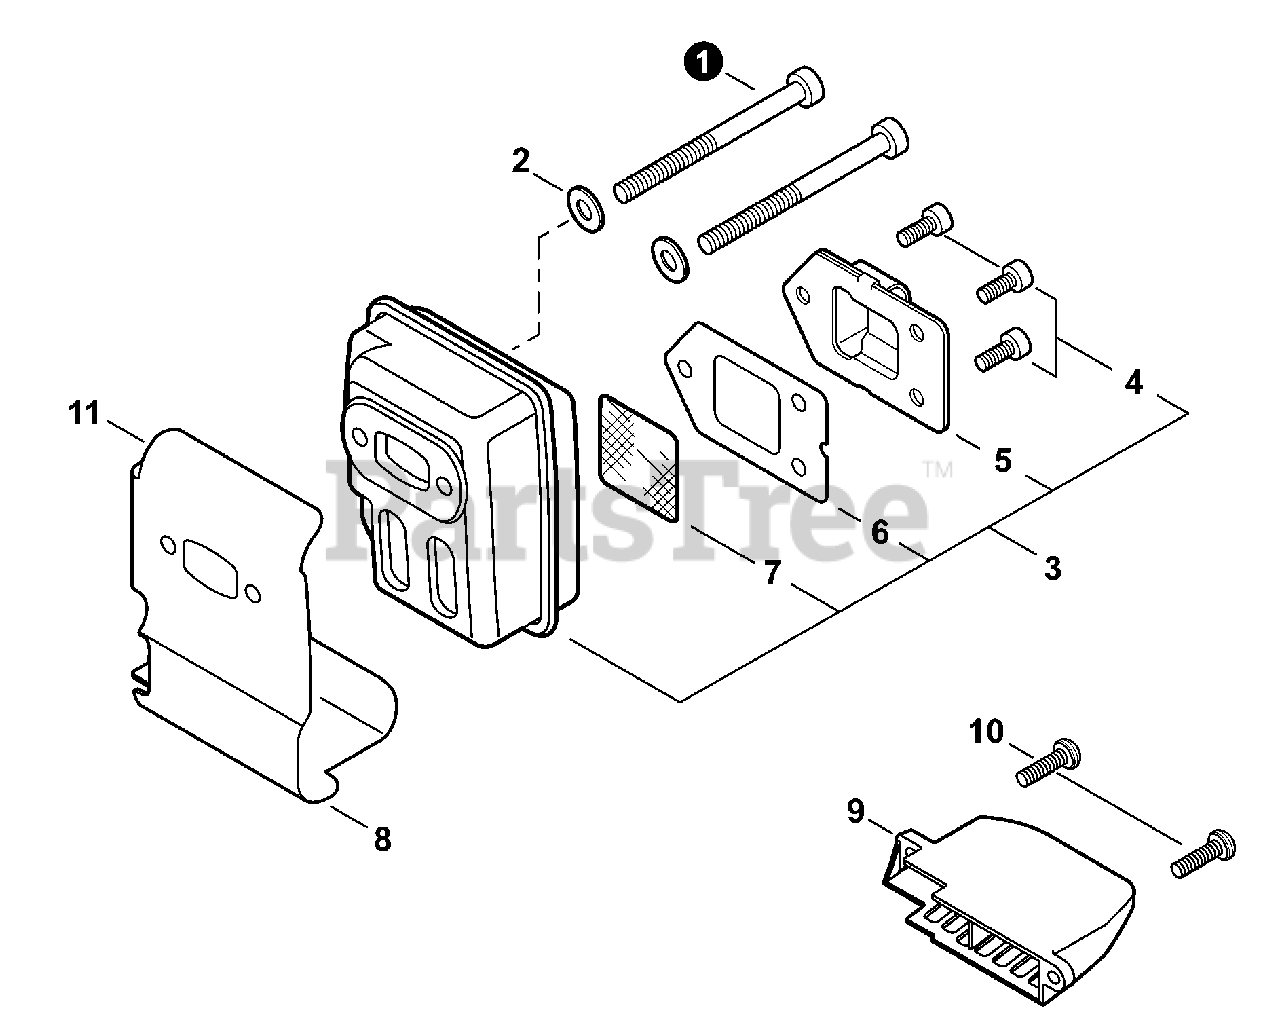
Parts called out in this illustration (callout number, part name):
1	BOLT, TORX 5×55
2	WASHER, FLAT 5.5×10×0.8
3	MUFFLER ASSY
4	BOLT, TORX 4×8
5	GUIDE, EXHAUST
6	GASKET, EXHAUST
7	SCREEN, SPARK ARRESTER
8	HEAT SHIELD, EXHAUST
9	COVER, MUFFLER
10	BOLT, TORX 5×16
11	GASKET KIT
